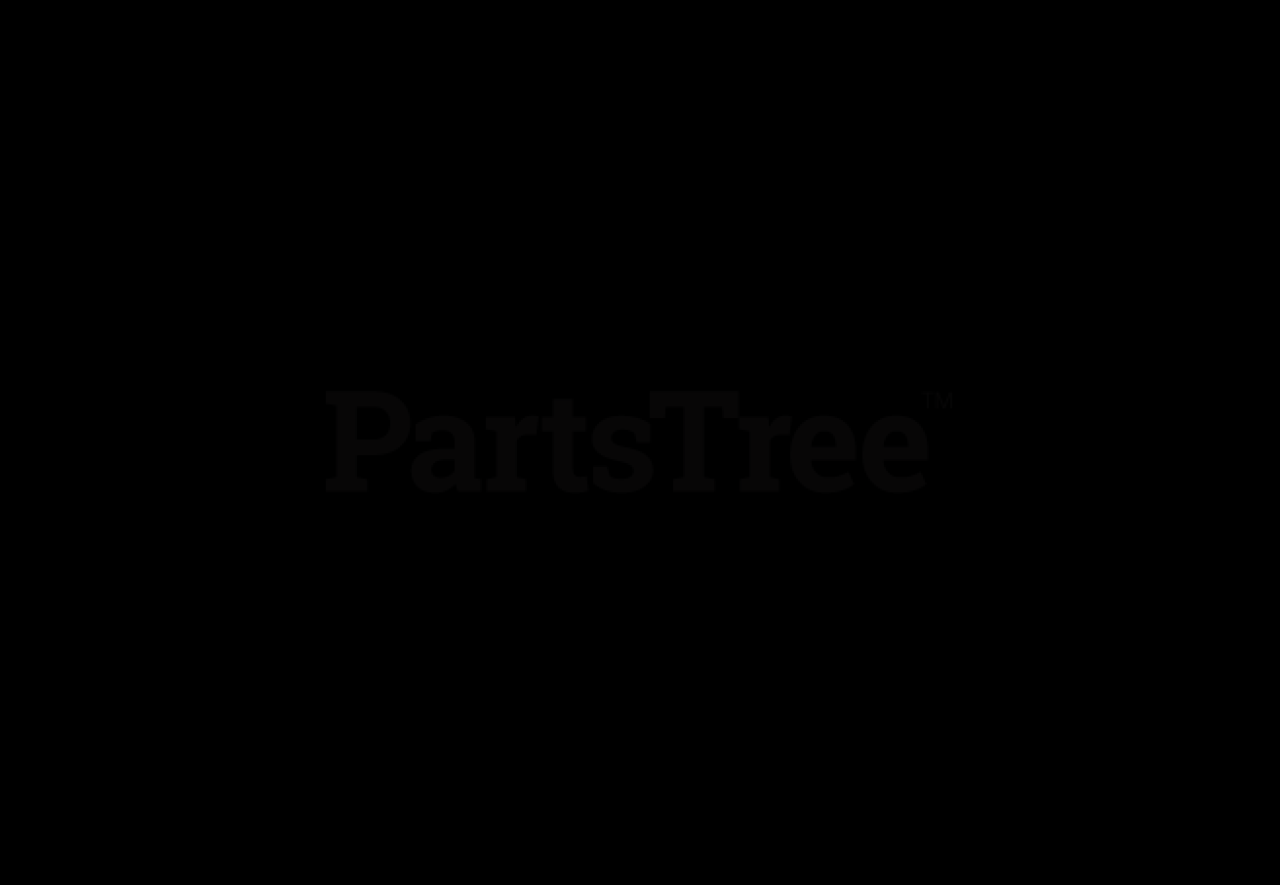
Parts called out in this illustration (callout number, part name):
1	Pump, Hydraulic (RTN) with Auxiliary
2	Key, Square 5 x 5 x 30mm Plain
3	Sheave, Poly V .671 x 4.125
4	Washer, Flat Steel .281 x 1.000 x .063
5	Washer, Locking .25 x .062
6	Bolt, Hex M6 x 1 x 12, YZ EP30
7	Screw, Socket Head .25-20 x .50 EP80
8	Bolt, Hex .50-13 x 1.50 Grade 5
9	Bolt, Hex .31-18 x 2.50 Grade 5
10	Nut, Locking Top Flange .50-13
11	Pump, Hydraulic (RTN)
12	Assembly, Idler Arm Guard Drive (Includes 13 & 14)
13	Weldment, Idler Arm Ground Drive
14	Bushing, 1.00 x 1.125 x 1.936
15	Fan, Hydro Pump Cooling
16	Spring, Tension .120 x .845 x 6.500
17	Washer, Flat Steel .39 x .75 x .125
18	Bolt, Hex .50-13 x 3.50 Grade 5
19	Bearing, Pedestal Powdered Metal
20	Washer, Flat Steel .406 x .812 x .065
21	Assembly, Idler 4"
22	Bolt, Hex .38-16 x 2.0 Grade 5
23	Kit, Pump Seal (One kit required for each pump)
24	Nut, Locking Top Flange .38-16
25	Bolt, Hex .31-18 x 1.25 Grade 5
26	Nut, Hex .31-18
27	Nut, Locking Top Flange .31-18
28	Belt, Poly-V 49.50, Hydrostatic 200Z Series
